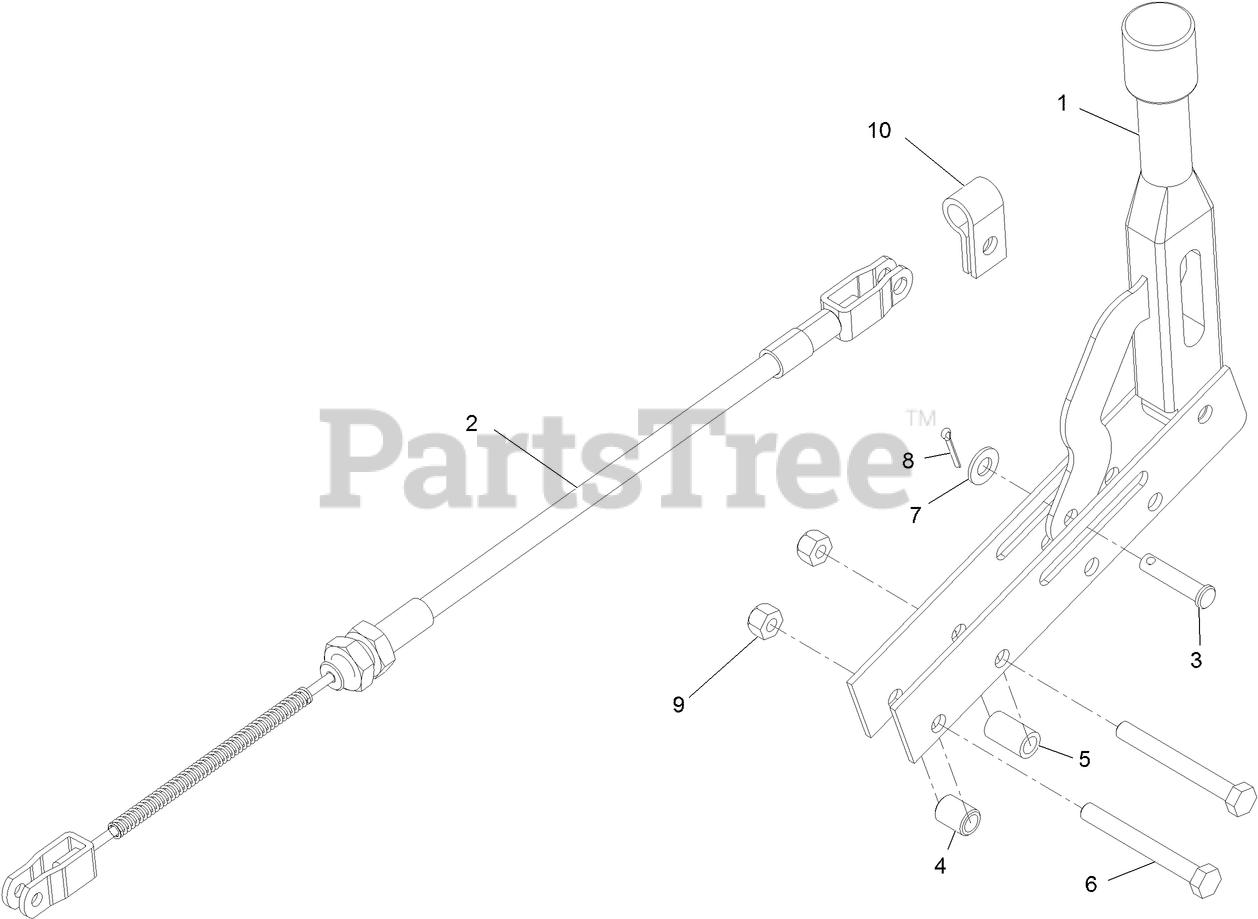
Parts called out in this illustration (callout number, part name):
1	LEVER-BRAKE
2	CABLE-BRAKE
3	PIN-CLEVIS
4	SPACER-LEVER, CONTROL
5	SPACER-IDLER
6	SCREW-HH
7	WASHER-PLAIN
8	PIN-COTTER
9	NUT-LOCK, NI
10	CLAMP-CONDUIT
